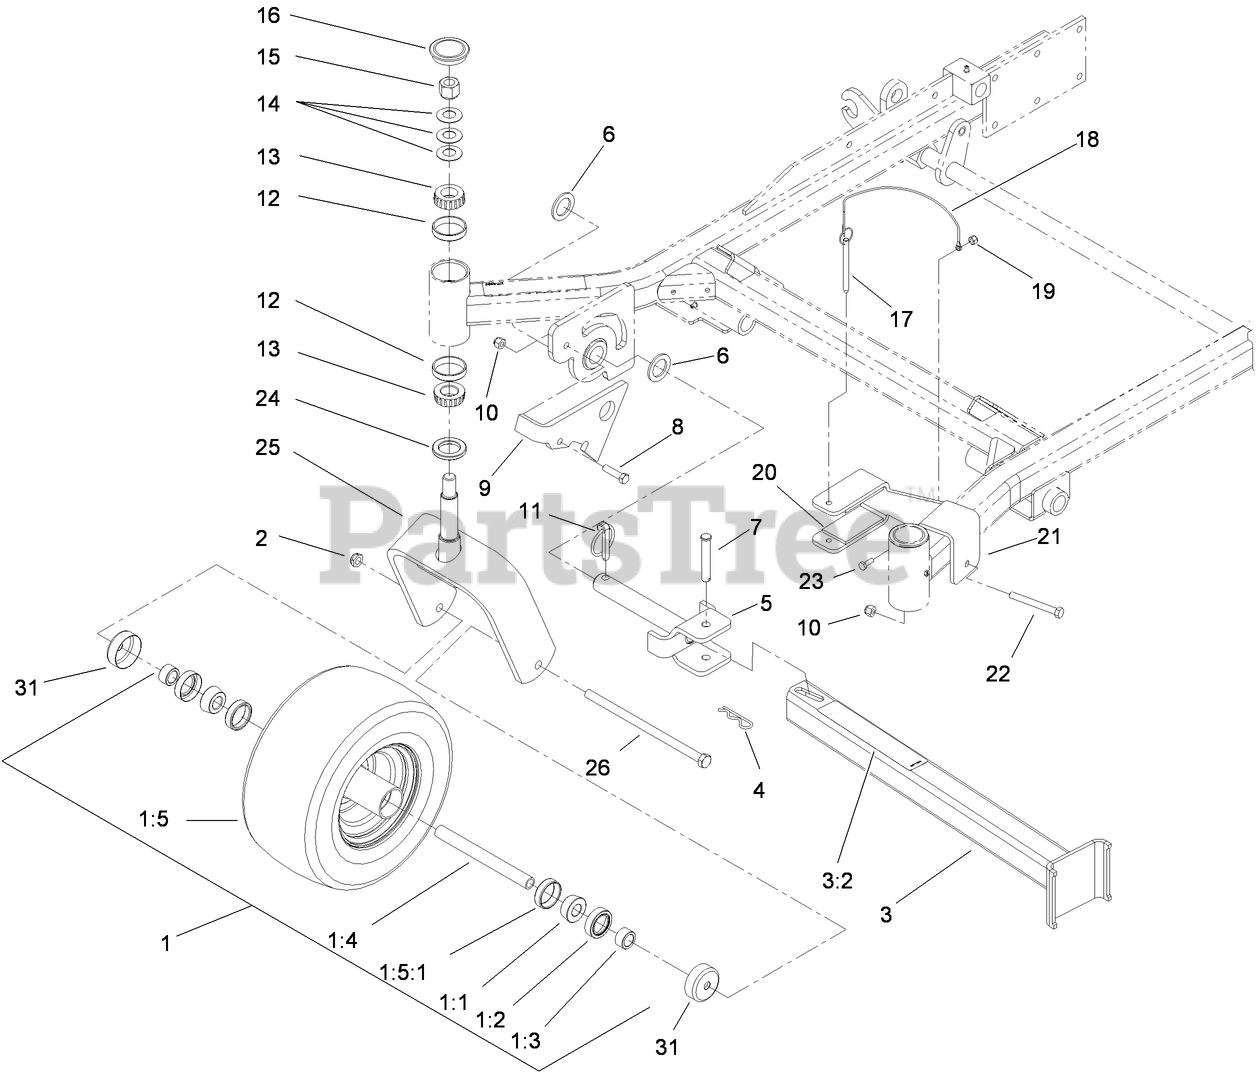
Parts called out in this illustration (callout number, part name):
1	WHEEL AND TIRE ASM
1:1	BEARING-CONE, TAPER
1:2	SEAL-CASTER
1:3	SPACER-NUT
1:4	AXLE-CASTER
1:5	WHEEL AND TIRE ASM
1:5:1	BEARING-CUP
2	NUT-LOCK, NI
3	Leg ASM
3:2	DECAL-Z STAND
4	PIN-HAIR
5	PIN-PIVOT
6	WASHER-THRUST
7	PIN-CLEVIS
8	SCREW-HH
9	BRACKET-LATCH
10	NUT-LOCK, NI
11	PIN-LYNCH
12	BEARING-CUP, TAPERED
13	BEARING-CONE, TAPERED
14	WASHER-BELLVILLE
15	NUT-LOCK, NI
16	CAP-GREASE
17	PIN-HITCH, COTTERLESS
18	LANYARD-NYLON
19	NUT-LOCK, NI
20	Cushion-Rubber
21	BRACKET-CRADLE
22	SCREW-HH
23	SCREW-HH
24	SEAL-GREASE
25	CASTER-FORK
26	Screw-HH
31	GUARD-SEAL
